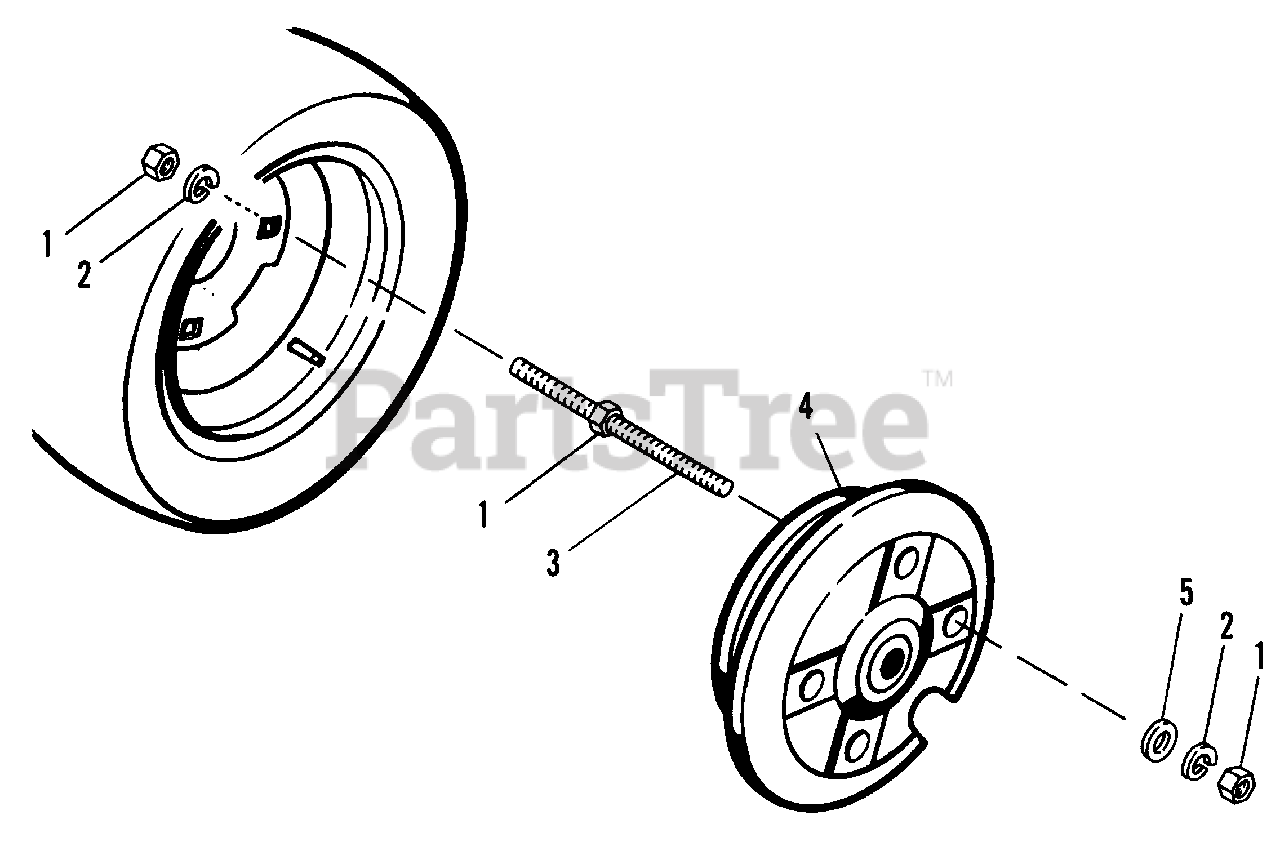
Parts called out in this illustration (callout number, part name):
1	NUT, Hex, Full, 1/2-13
2	LOCKWASHER, 1/2
3	ROD, Threaded
4	WEIGHT, Wheel
5	WASHER, Plain, 1/2 (1690411)
5	WASHER, 1/2 (1691352)
